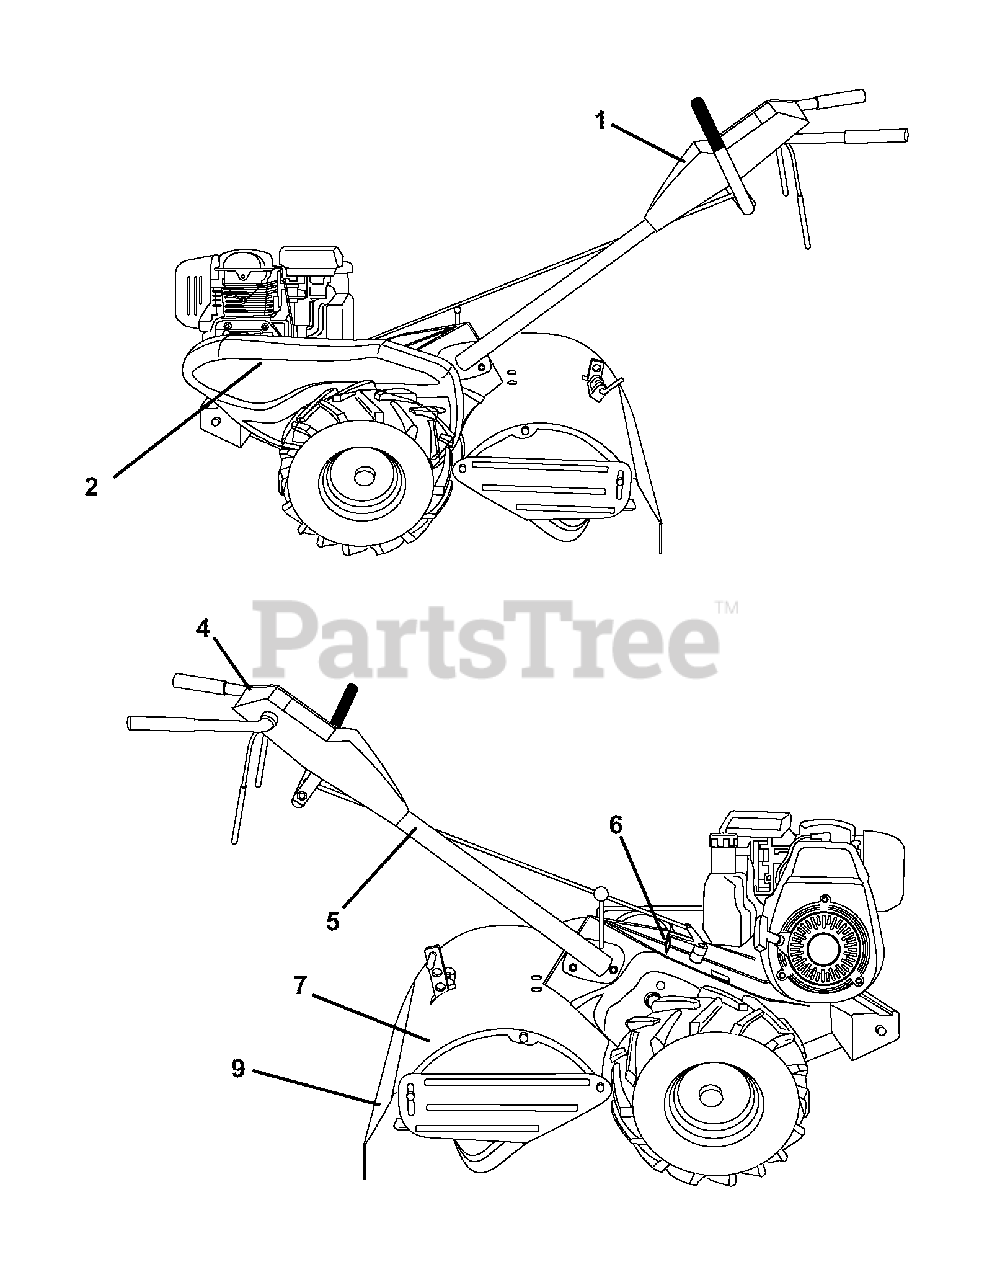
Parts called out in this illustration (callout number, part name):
1	Decal, Logo, Control Panel
2	Decal, Logo, Belt Guard
4	Decal, Instruction, Tilling
5	Decal, Hand Placement
6	Decal, Shift Indicator
7	Decal, Caution
9	Decal, Warning, Rotating Tines
